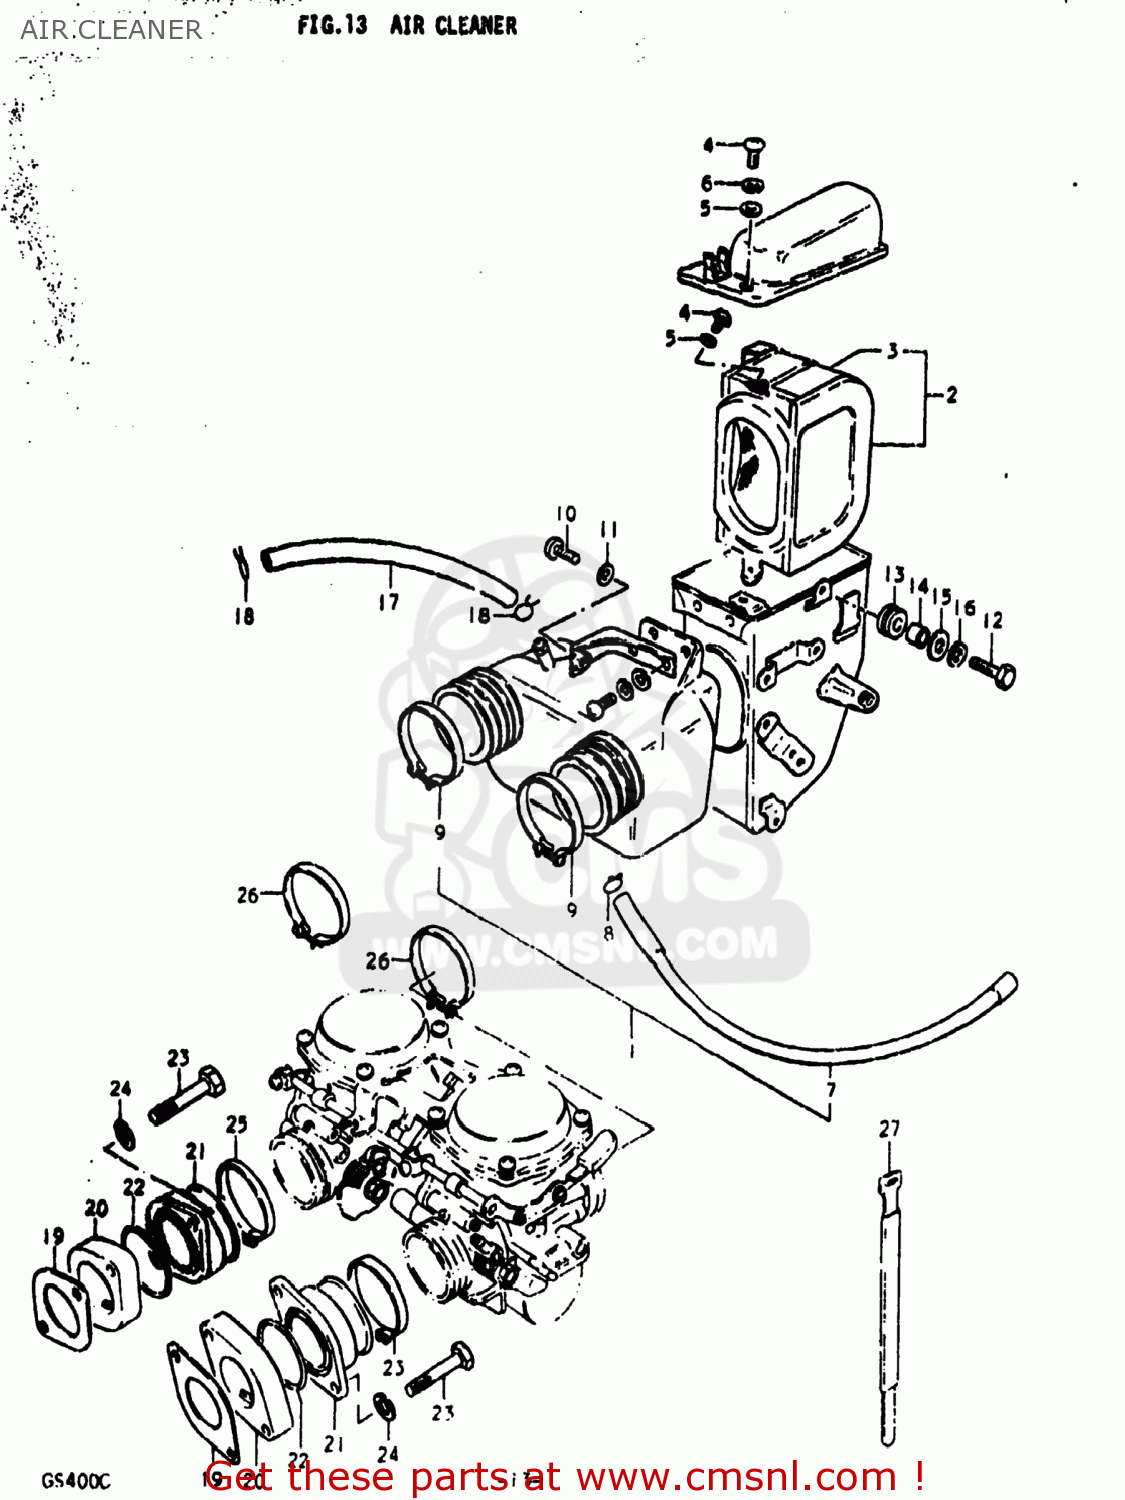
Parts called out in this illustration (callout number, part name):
1	CLEANER ASSEMBLY,AIR
2	FILTER ASSY
3	FILTER
4	SCREW
5	WASHER
6	LOCK WASHER
7	HOLDER,FILTER
8	HOSE,AIR CLEANER
9	CLAMP
10	SCREW
11	WASHER
12	BOLT
13	CUSHION
14	SPACER (6.1X9X9)
15	WASHER
16	LOCK WASHER
17	HOSE
18	CLIP
19	GASKET,CARBURETOR (NAS)
20	INSULATOR,CARBURETOR
21	PIPE,INTAKE
22	O-RING (D:2.4 ID:39.7)
23	BOLT
24	LOCK WASHER
25	CLAMP
26	CLAMP
27	CLAMP
